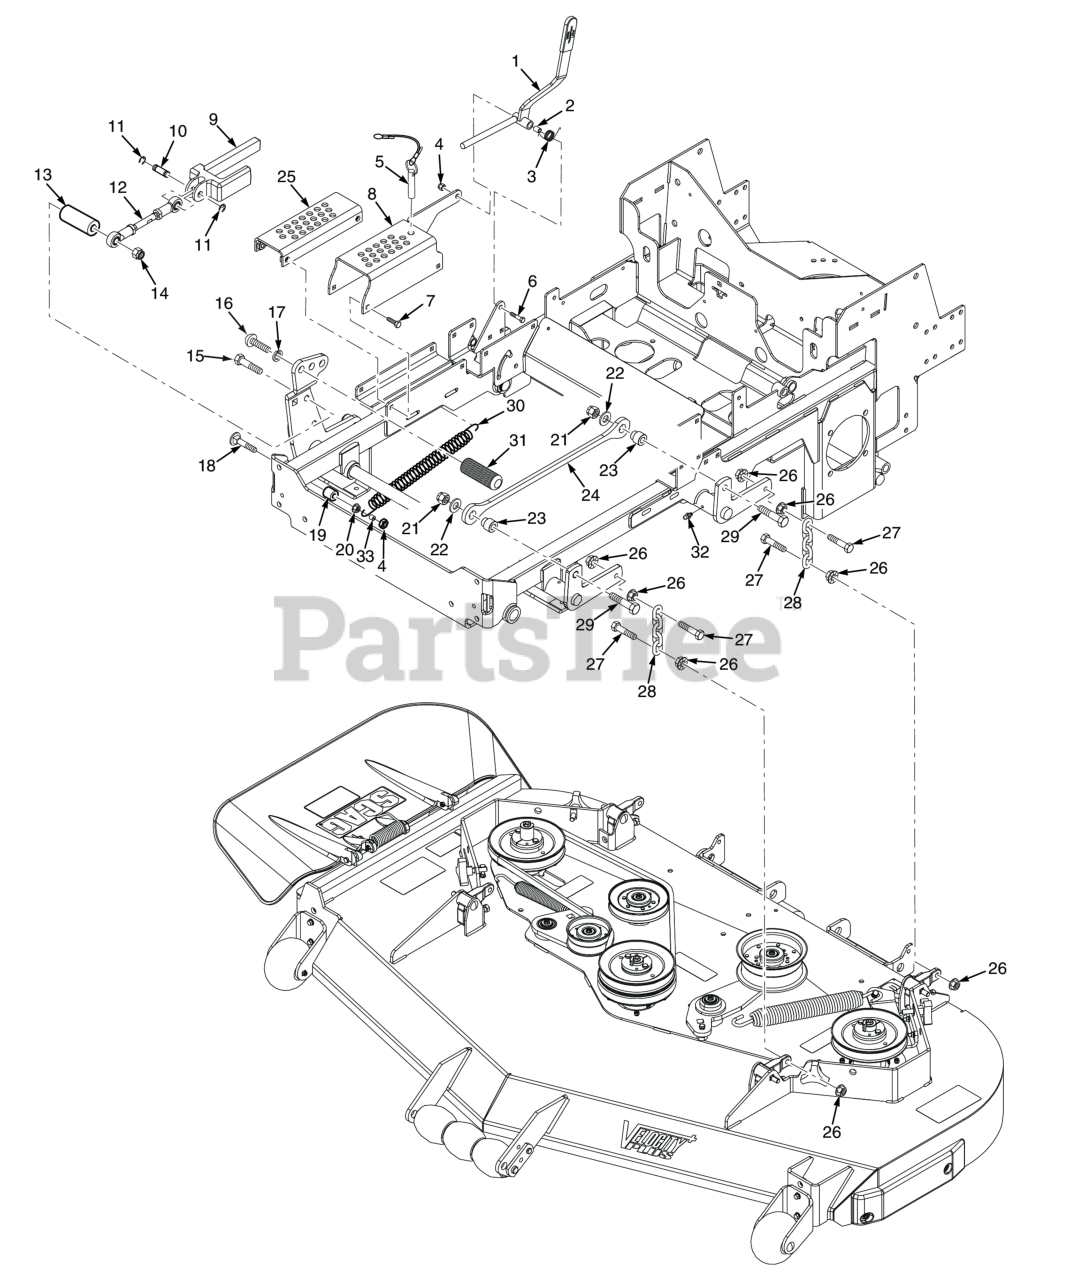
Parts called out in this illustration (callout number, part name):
1	Deck Latch Assembly (Includes Grip)
2	Spacer, Deck Latch
3	Spring, Torsion - Lever Return
4	Bolt, Hex Head 3/8-16 x 1" Ser. Flg.
5	Lanyard, Deck Height Pin Assembly
6	Capscrew, Hex Head 3/8-16 x 2-1/2"
7	Bolt, Hex Wshr Head 5/16-18 x 1-1/4"
8	Adjustment Bracket, Cutting Height
9	Slide, Height Adjust (INCL. 10,11,12)
10	Pin, Deck Lift
11	Retaining Ring, 1/2" Ext. "E"
12	Linkage Assembly, Deck Lift
13	Spacer, Deck Lift Pedal
14	HEX LOCKNUT, ELASTIC STOP, 1/2-13
15	Bolt, Hex Head 1/2-13 x 4" (lower)
16	Capscrew, 5/8-11 x 1-1/2"
17	Lockwasher, 5/8" Spring
18	Carriage Bolt, 3/8-16 x 2-1/2"
19	Yoke, Front Caster Wheel
20	NUT, 3/8-16 SERRATED FLANGE HEX HEAD
21	HEX LOCKNUT, ELASTIC STOP, 1/2-13
22	Flat Washer, 1/2 (.562 x 1.375 x .109)
23	Pivot, Deck Link
24	Link, Decklift (black)
25	Adjustment Bracket, Lower Cut Height
26	NUT, 3/8-16 SERRATED FLANGE HEX HEAD
27	Bolt, Hex Head 3/8-16 x 1-1/2" B&S 32BV
28	Chain, Deck Lift
29	Bolt, Hex Head 1/2-13 x 2-1/4"
30	Spring, Decklift
31	Foot Pedal, Height Adjustment
32	GREASE FITTING, STR. 1/4-28 SELF TAP.
33	Spacer, Deck Assist
